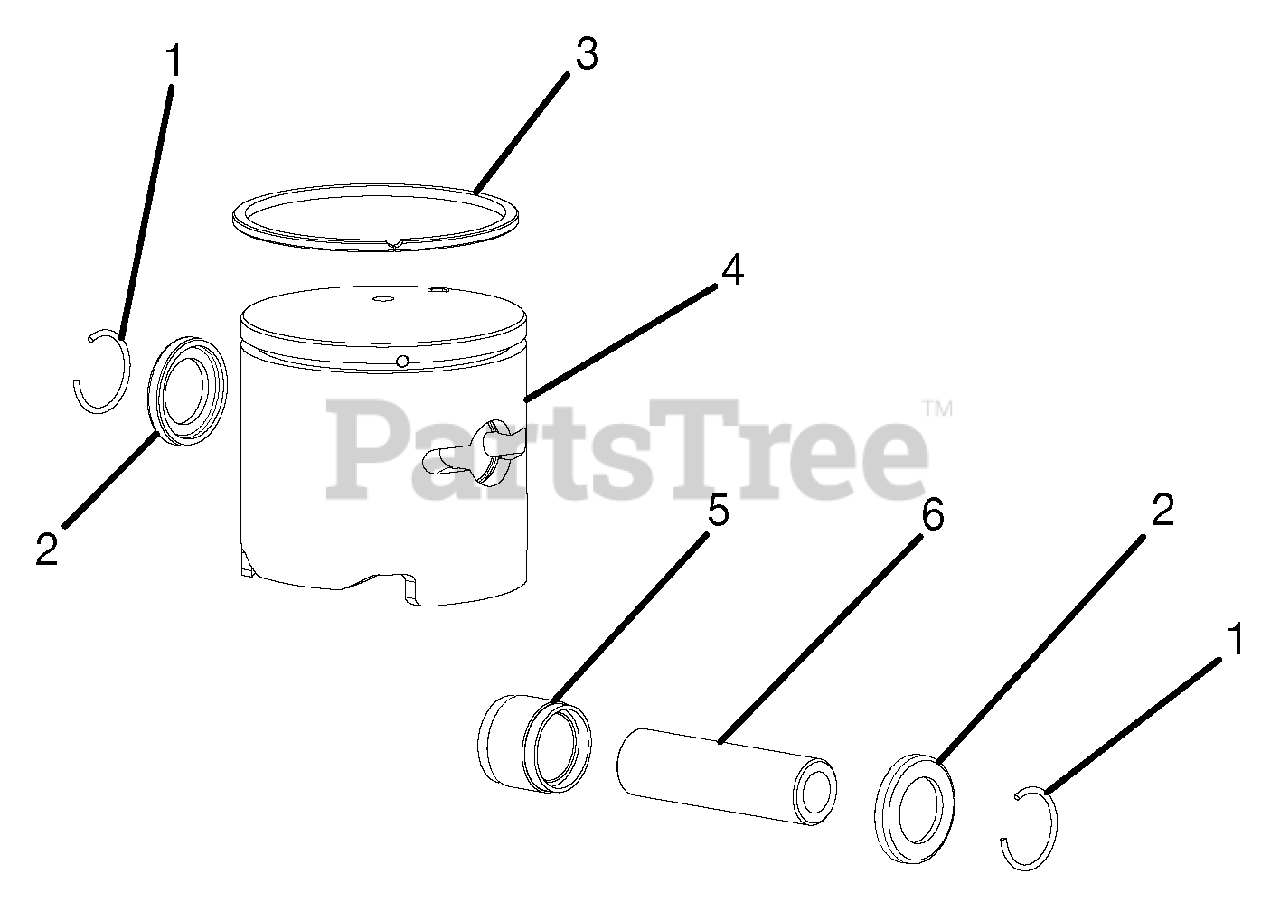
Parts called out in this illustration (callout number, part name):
1	WRIST PIN CLIP RING
2	WASHER
3	PISTON RING
5	NEEDLE BEARING (ID 8 X 8.8)
6	WRIST PIN
